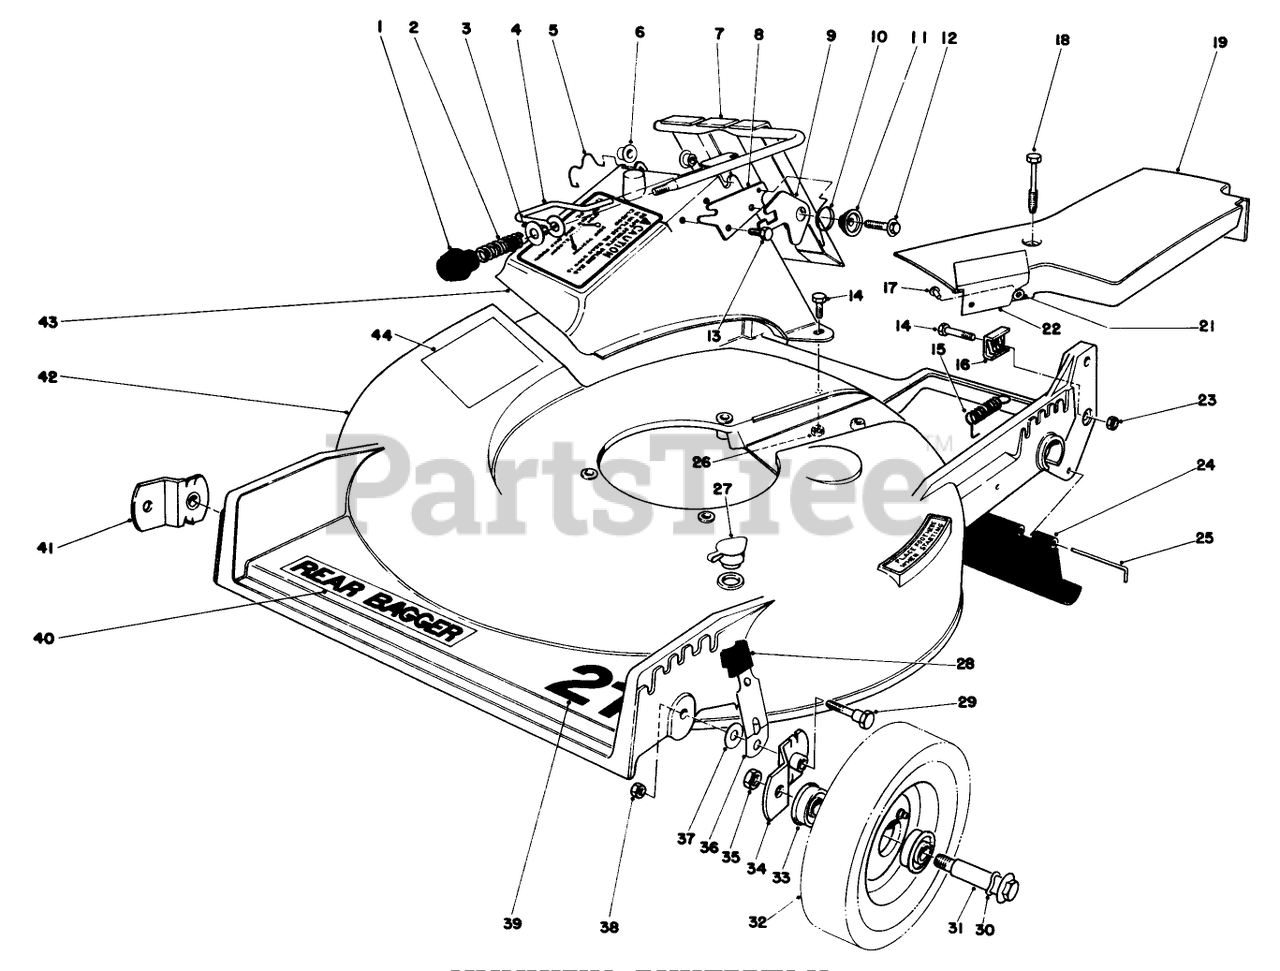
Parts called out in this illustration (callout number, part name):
2	COMPRESSION SPRING
3	WASHER
4	DOOR LATCH
5	DOOR RETAINER
6	BUSHING-NYLON
8	DOOR LATCH PLATE
10	TORSION SPRING
13	SCREW-HWH
14	SCREW-HH
15	IDLER SPRING
16	CLAMP-CABLE
17	RIVET-HEAD, FLAT
18	SCREW-HWH
21	WASHER-FLAT
23	NUT-JAM
24	SHIELD - TRAILING
26	NUT-LOCK, NI
27	WASHOUT PLUG
28	KNOB-ARM
29	PIVOT SCREW
30	SPRING WASHER
33	BEARING-BALL
34	PIVOT ARM ASM A
37	WASHER-PIVOT
41	PIVOT ARM ASM
43	DISCHARGE CHUTE *B
